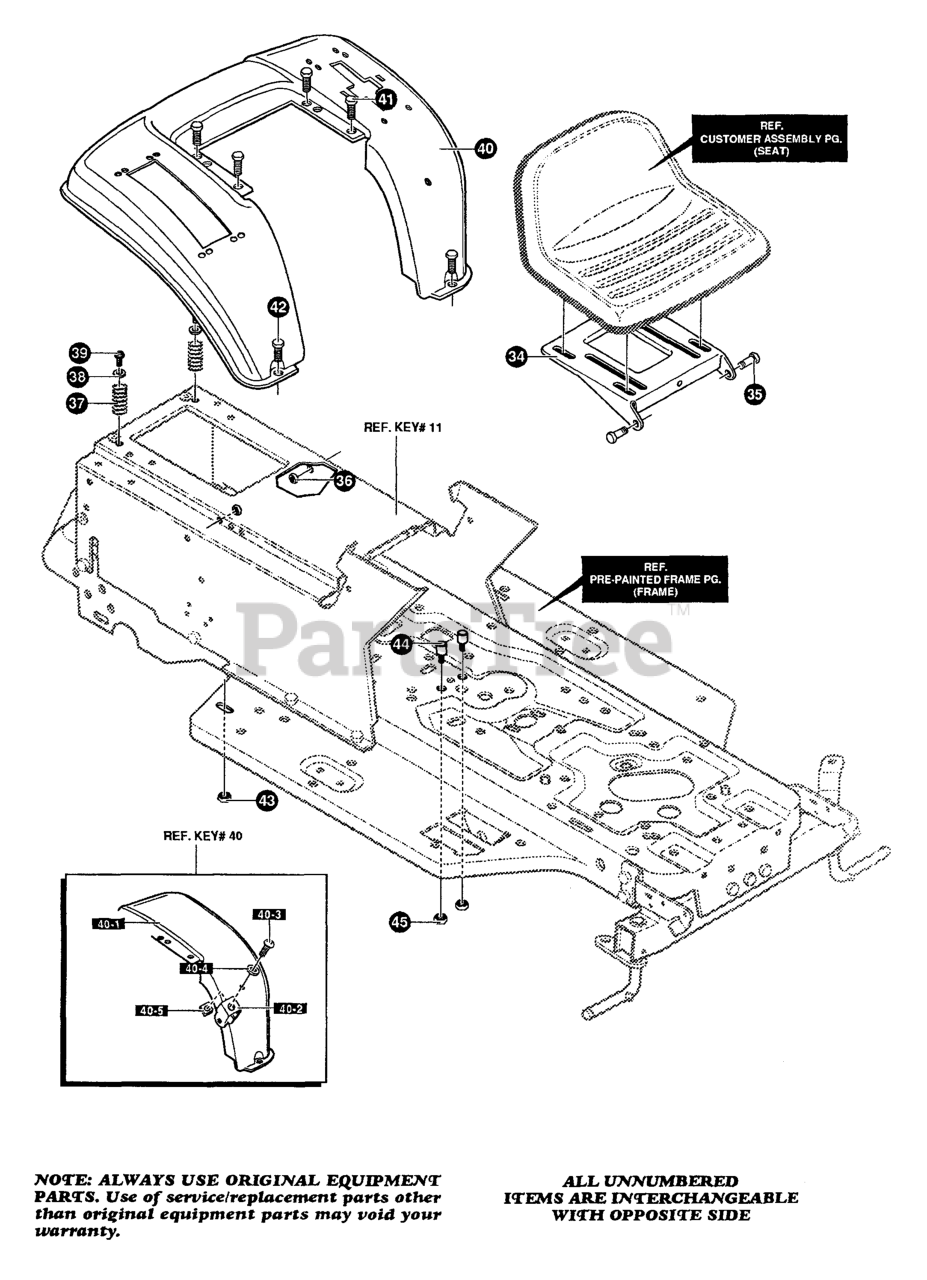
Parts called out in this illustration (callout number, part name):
34	PLATE, SEAT
35	BOLT, .437 X .156
36	NUT, 5/16-18
37	SPRING, SEAT
38	WASHER, FLAT .281 X .63 X .065
39	SCREW, 1/4-20 X .50
40	ASSEMBLY, FENDER
40-2	CLEVIS
40-3	SCREW, 5/16-18 x 0.56
40-4	WASHER, .344ID X 1.50D X .09
40-5	NUT, 5/16-18 SQ
41	SCREW, 1/4-20 x .50
42	BOLT, 5/16-18 X 1.00
43	NUT, 5/16-18
44	PIN, 5/16-18 HOOD LATCH
45	NUT, 5/16-18
